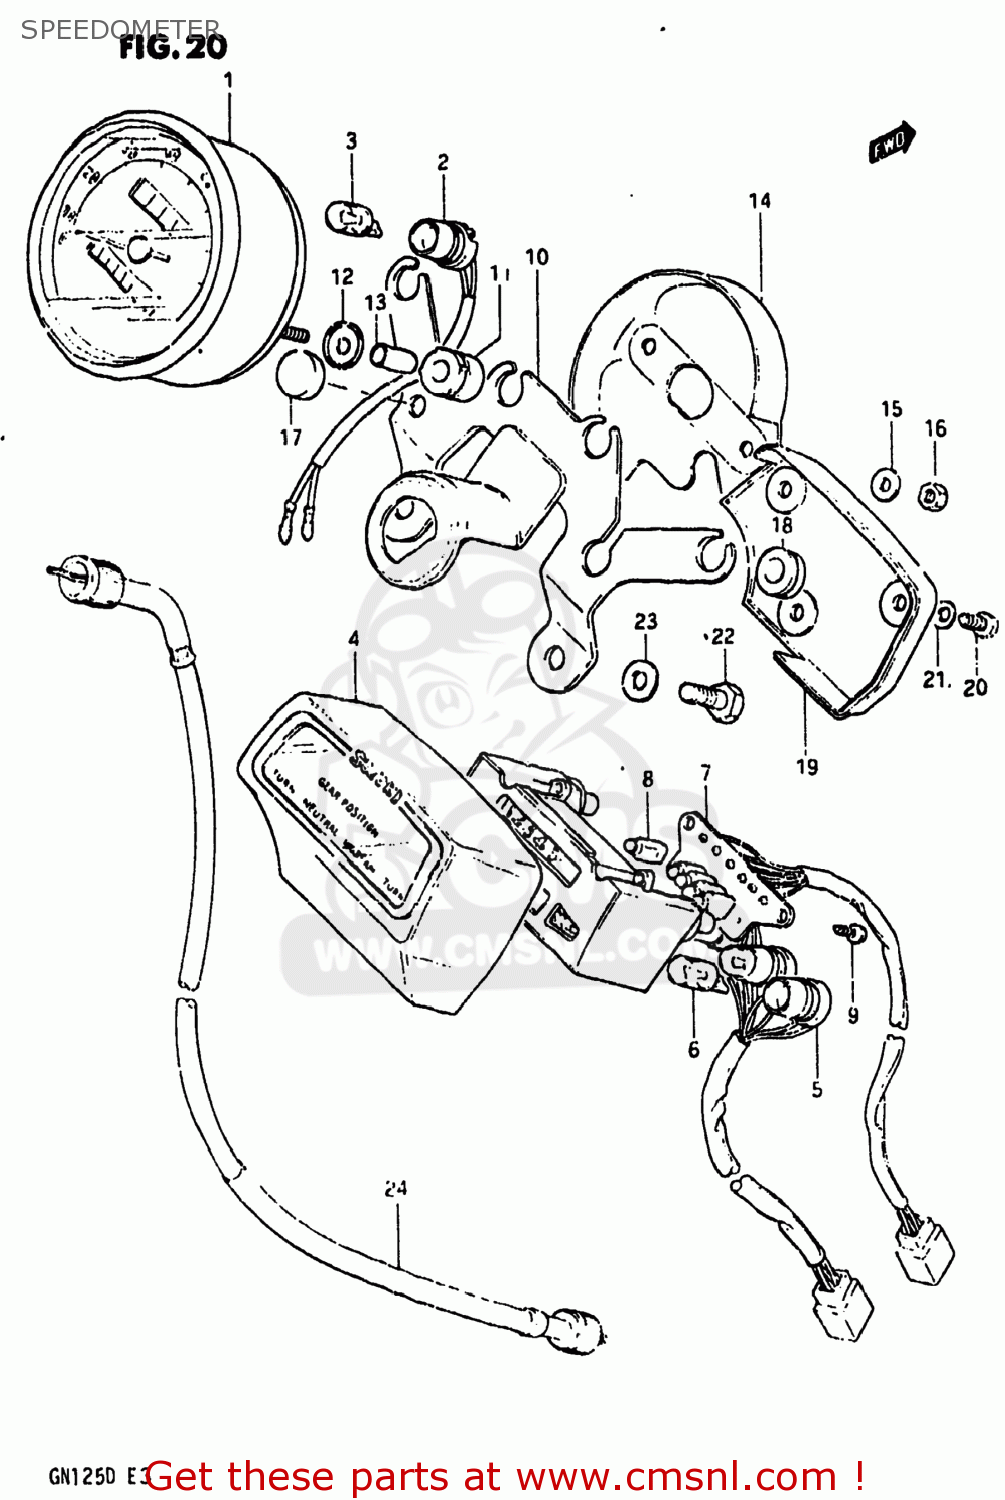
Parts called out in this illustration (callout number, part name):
1	METER,SPEED (KM/MPH)
2	SOCKET,SPEEDOMETER
3	BULB(12V3.4W,T10,BF175-01450A)
4	CASE,PILOT BOX
5	SOCKET,METER
6	BULB(12V3.4W,T10,BF175-01450A)
7	SOCKET,GEAR INDICATOR
8	BULB(14V1.12W)
9	SCREW,GEAR INDICATOR
10	BRACKET,METER
11	CUSHION,METER
12	WASHER
13	SPACER,SPEEDOMETER
14	UNDER COVER,SPEEDOMETER
15	WASHER,METER
16	NUT
17	CUSHION,METER
18	CUSHION
19	COVER,PILOT BOX,UNDER
20	SCREW
21	WASHER
22	BOLT, UPPER
23	WASHER
24	CABLE ASSEMBLY,SPEEDOMETER
